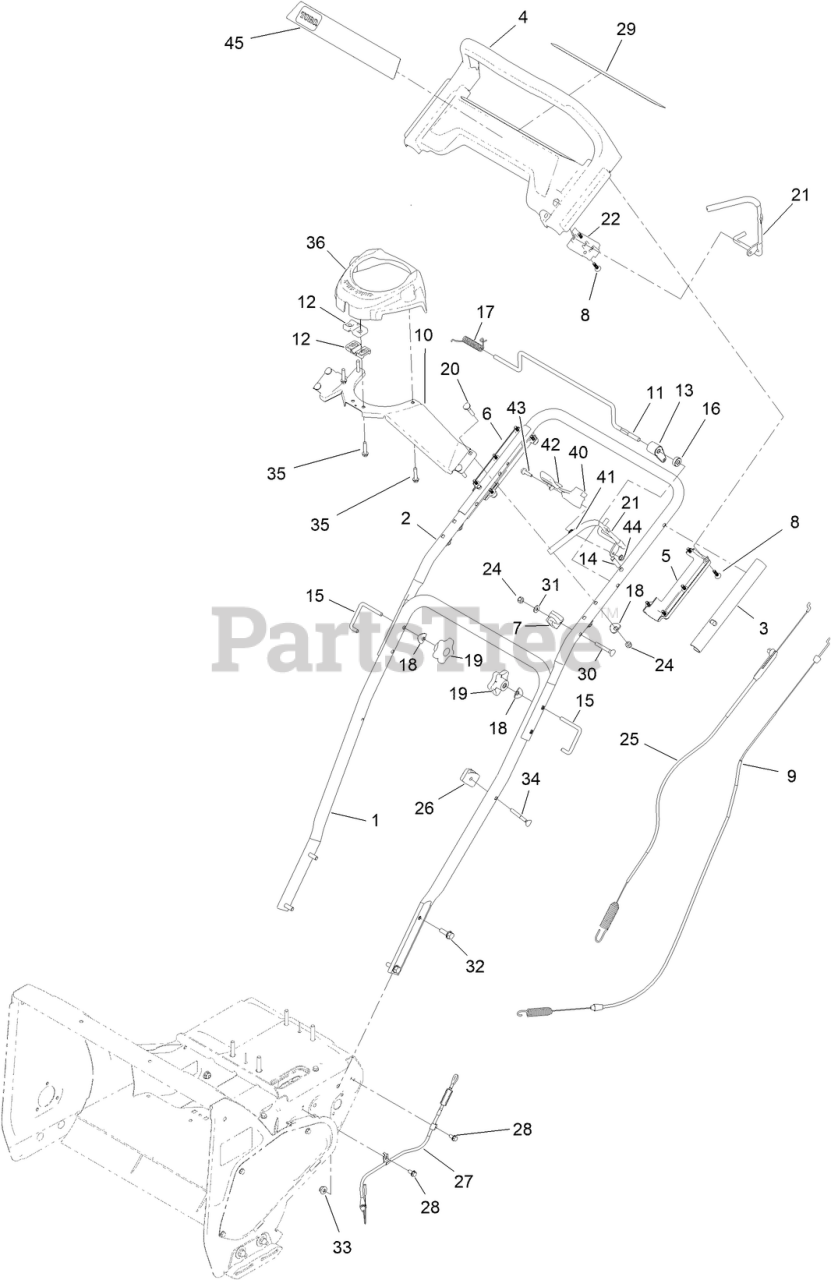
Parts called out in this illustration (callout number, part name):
1	HANDLE-LOWER
2	HANDLE-UPPER
3	SLEEVE HANDLE
4	HANDLE PP ASM W/ DECAL
5	HANDLE-BOTTOM, LH
6	HANDLE-BOTTOM, RH
7	CABLE-GUIDE
9	CABLE-TRANSMISSION
10	BRACKET-CHUTE, CONTROL
11	BAR-CONTROL, TRACTION
12	SUPPORT-ROD
13	LEVER-TRACTION
14	PIN-DOWEL
15	LOCK-HANDLE
16	SPACER
17	SPRING-TORSION
18	WASHER-CUP
19	KNOB-HANDLE
20	SCREW-HANDLE
21	ASM-BAIL
22	BAIL-MOUNT
24	NUT-HEX
25	CABLE-ROTOR, UPPER
26	ANCHOR-CABLE, UPPER
27	CABLE-ROTOR, LOWER
28	SCREW-HWH
29	DECAL-CONTROL, PANEL
30	BOLT-CARR
31	WASHER-FLAT
32	SCREW-HHF
33	NUT-HF
34	SCREW-HANDLE
35	SCREW-PLASTIC,HWH
36	HEADLIGHT-SNOWMASTER
41	SPRING-TORSION
43	SCREW-SHOULDER
44	NUT-HEX FLANGE
45	DECAL-DISPLAY
